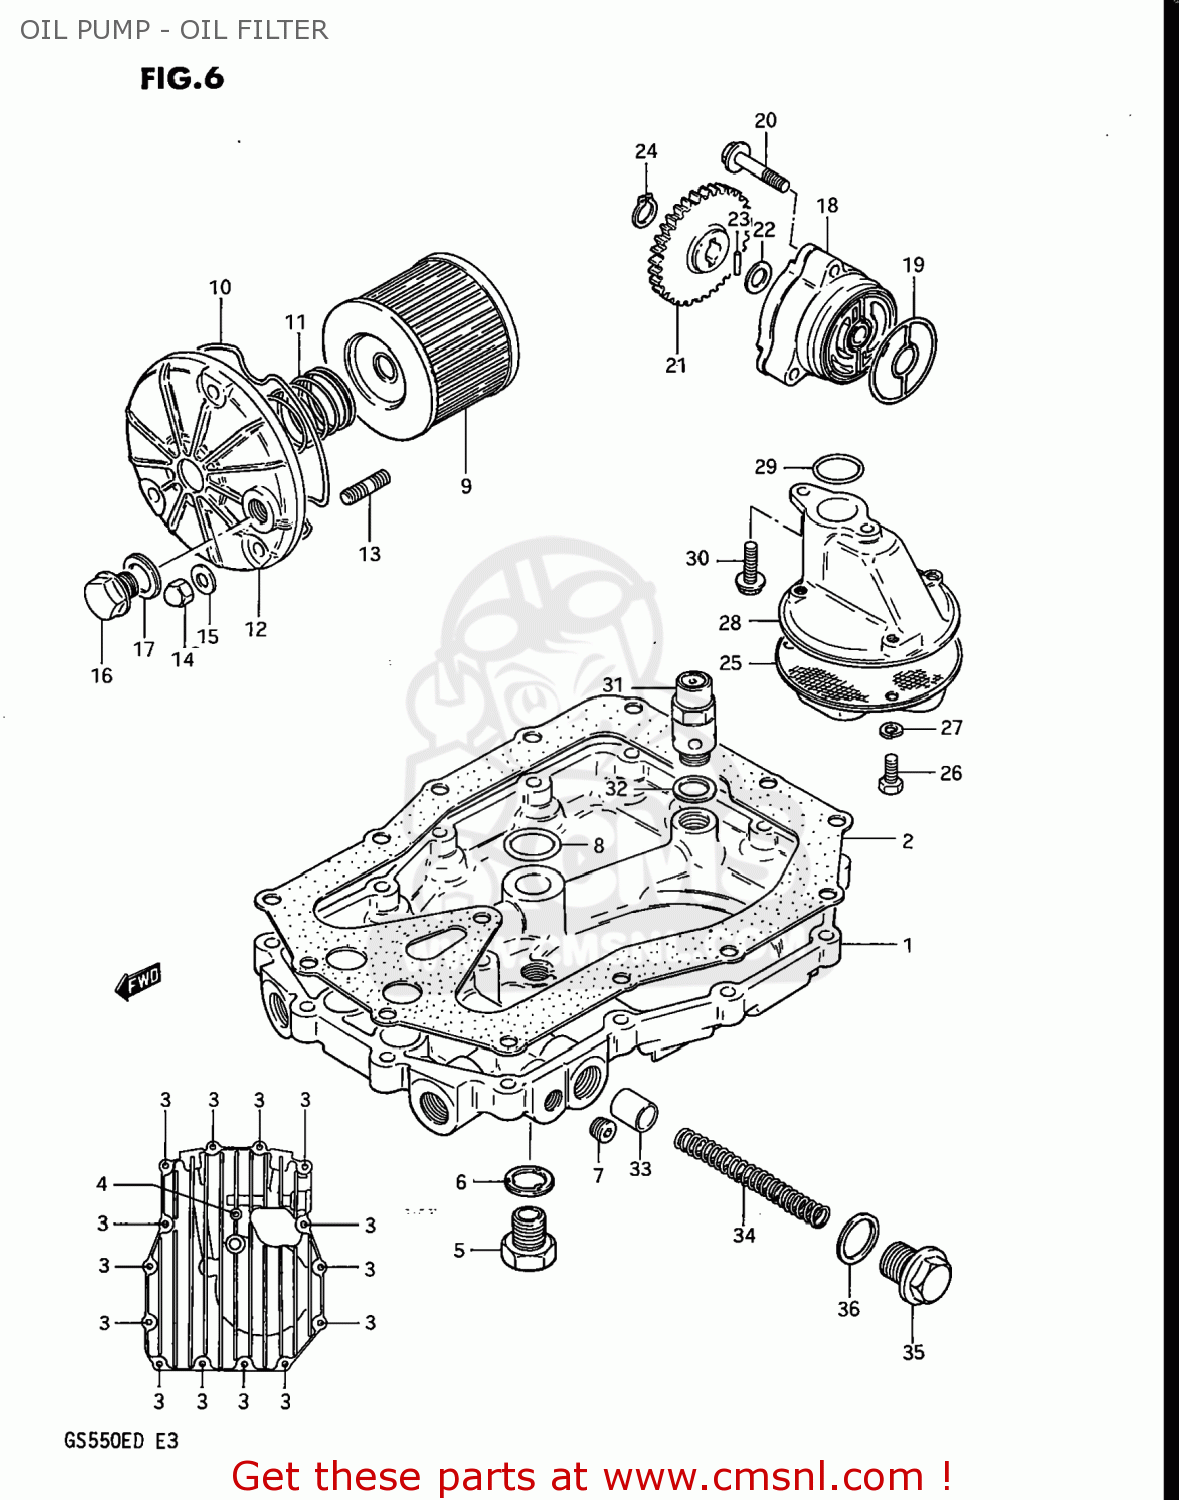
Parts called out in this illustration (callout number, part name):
1	PAN,OIL
2	GASKET,OIL PAN (MCA)
3	BOLT
4	BOLT 6X35
5	PLUG
6	GASKET(14X19.2X2) (NAS)
7	PLUG
8	O RING(D:3.2,ID:17.8)
9	FILTER ASSY,ENGINE OIL
10	O RING,OIL FILTER CHAMBER CAP
11	SPRING
12	CAP,OIL FILTER
13	STUD 6X20
14	NUT 6MM
15	WASHER
16	PLUG(14X12)
17	GASKET(14X19.2X2) (NAS)
18	PUMP ASSEMBLY,ENGINE OIL
19	O-RING,OIL PUMP
20	BOLT(6X32)
21	GEAR,OIL PUMP DRIVEN
22	SHIM
23	PIN(4X15.8)
24	CIRCLIP
25	STRAINER,ENGINE OIL
26	BOLT
27	LOCK WASHER
28	PROTECTOR,OIL STRAINER
29	O RING(D:3.2,ID:17.8)
30	BOLT,REAR
31	REGULATOR ASSEMBLY,ENGINE
32	WASHER
33	PLUNGER,CONTROL
34	SPRING
35	PLUG
36	O RING(D:2.4,ID:16.8)
